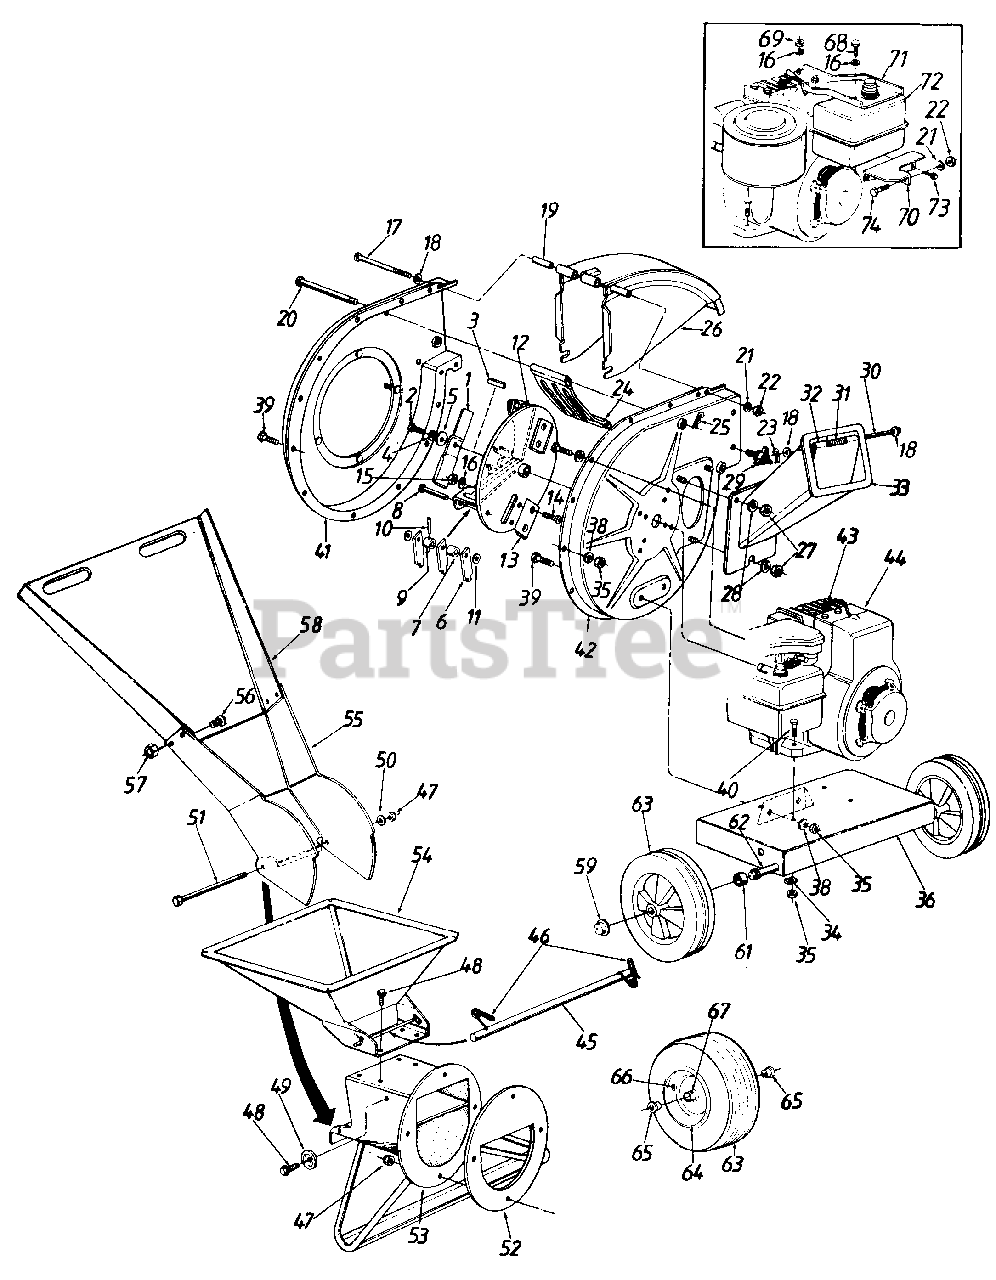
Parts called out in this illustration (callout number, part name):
3	Sq. Key 1/4 x 2.0" Lg.
4	L-Wash. 3/8" I.D. H.D.
5	Fl-Wash. .406" I.D. x 1.25" O.D. Hdn.
6	Flail
7	Flail Spacer
8	Clevis Pin .496" Dia.
9	Flail Spacer w/.160" Dia. Hole
10	Spring Roll Pin 1.12" Lg.
11	Fl-Wash. .531" I.D. x .94" O.D.
12	Impeller Ass'y.
13	Chipper Bladet
14	Flat Hd. Scr. 5/16-24 x .75" Lg.
15	Hex Nut 5/16-24 (Grade 5)
16	L-Wash. 5/16" I.D.
17	Hex Bolt 1/4-20 x 4.0" Lg.
18	Fl-Wash. .344" I.D. x.875" O.D.
19	Chute Hinge Spacer 1.66" Lg.
20	Clevis Pin .5" Dia. x 4.62" Lg.
21	L-Wash. 1/4" I.D.
22	Hex Nut 1/4-20 Thd.
23	Cap Speed Nut 1/4" Rodt
25	Internal Cotter Pin 3/8" Dia.
27	Hex Nut 5/16-18 Thd. (Grade 5)
28	Bell-Wash. .345" I.D. x .88"
29	Hand Knob
30	Chipper Door Rod
31	Torsion Spring 1.14" Lg.
35	Hex Nut 5/16-18 Thd. (Grade 5)
36	Shredder Frame
38	L-Wash. 5/16" I.D.
39	Hex Bolt 5/16-18 x .75" Lg. (Grade 5)
40	Hex Bolt 5/16-18 x 1.75" Lg.
43	Spark Plug Boot
44	Engine
45	Release Bar
46	Torsion Spring 1.06" Lg.
47	Elastic Lock Nut 5/16-18 Thd.
48	Hex Wash. Hd. Self-Tap Scr. 5/16-18 x .75" Lg.
49	Stop Washer
50	Fl-Wash. 5/16" I.D.
51	Hex Bolt 5/16-18 x 8.38" Lg.
52	Back-Up Plate
53	Inlet Guide Ass'y.
56	Truss Mach. Scr. 1/4-20 x .5"
57	Hex L-Nut 1/4-20 Thd.
61	Spacer .64" I.D. x .38" Lg.
62	Shredder Axle
63	Wheel Ass'y. Comp.
64	Rim Only
65	Flange bearing .632" I.D.
66	Air Valve
67	Grease Fitting
68	Hex Bolt 5/16-18 x .625"
69	Hex Nut 5/16-18 Thd. Grade 5
70	Tank Support Brkt.
73	Hex Self-Tap Scr. #8 x .5"
74	Hex Bolt 1/4-20 x .62"
